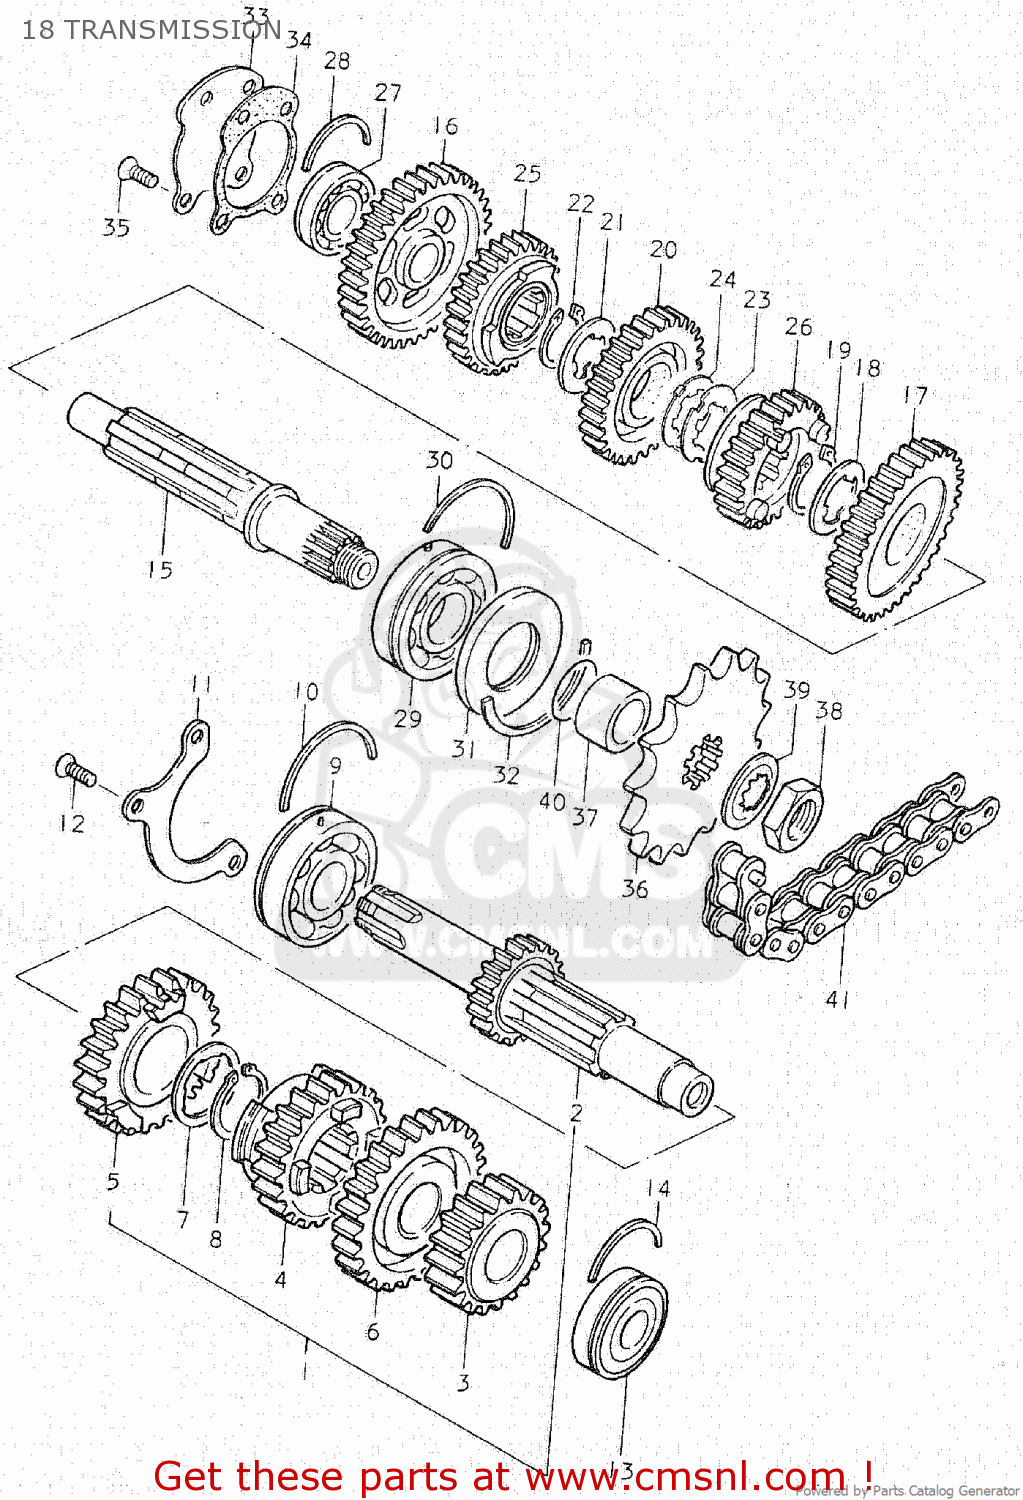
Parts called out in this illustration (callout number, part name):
1	SHAFT,COUNTER
2	SHAFT,COUNTER
3	GEAR,SECOND DRIVE
4	GEAR,THIRD DRIVE (NT:21)
5	GEAR,FOURTH DRIVE
6	GEAR,FIFTH DRIVE
7	WASHER,LOCK
8	CIRCLIP
9	BEARING(25X62X17)
10	C-RING
11	RETAINER,CNTR SHAFT BEARING
12	SCREW
13	BEARING(20X47X14)
14	C RING
15	SHAFT,DRIVE
16	GEAR,FIRST DRIVEN
17	GEAR,SECOND DRIVEN
18	WASHER,LOCK
19	CIRCLIP
20	GEAR,THIRD DRIVEN (NT:29)
21	WASHER,LOCK
22	CIRCLIP
23	WASHER,LOCK
24	WASHER
25	GEAR,FOURTH DRIVEN
26	GEAR,FIFTH DRIVEN
27	BEARING
28	C RING
29	BEARING(25X62X17)
30	C-RING
31	SEAL,OIL(32X62X7)
32	C RING
33	PLATE,DRIVE SHAFT
34	GASKET,DRIVESHAFT PLATE (MCA)
35	SCREW
36	SPROCKET,ENGINE (NT:15)
37	SPACER(25X32X18.6)
38	NUT
39	WASHER
40	O RING(D:1,ID:24.5)
41	CHAIN ASSEMBLY,DRIVE
